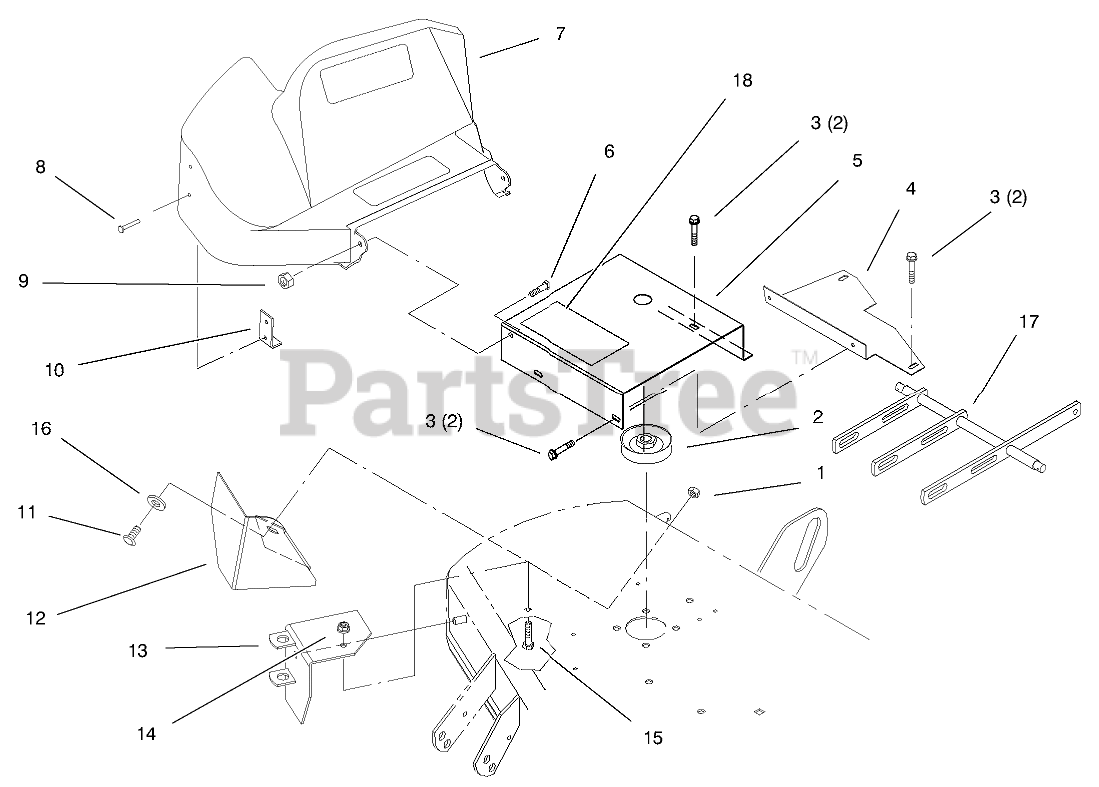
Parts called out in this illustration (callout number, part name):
1	NUT-LOCK, NI
2	PULLEY
3	SCREW-HWH
4	42" ADAPTOR SHIELD B
5	Inner Shield Asm. (Incl. Ref. #18)
6	SCREW-HH
7	SHIELD-BELT
8	RIVET-POP
9	NUT-LOCK, NI
10	BRACKET-SUPPORT, SHIELD
11	SCREW-HH
12	42" DEFLECTOR B
13	PIVOT SUPPORT ASM
14	NUT-HF
15	SCREW-HH
16	WASHER-FLAT
17	Bar-Leveler
18	DECAL-DANGER
